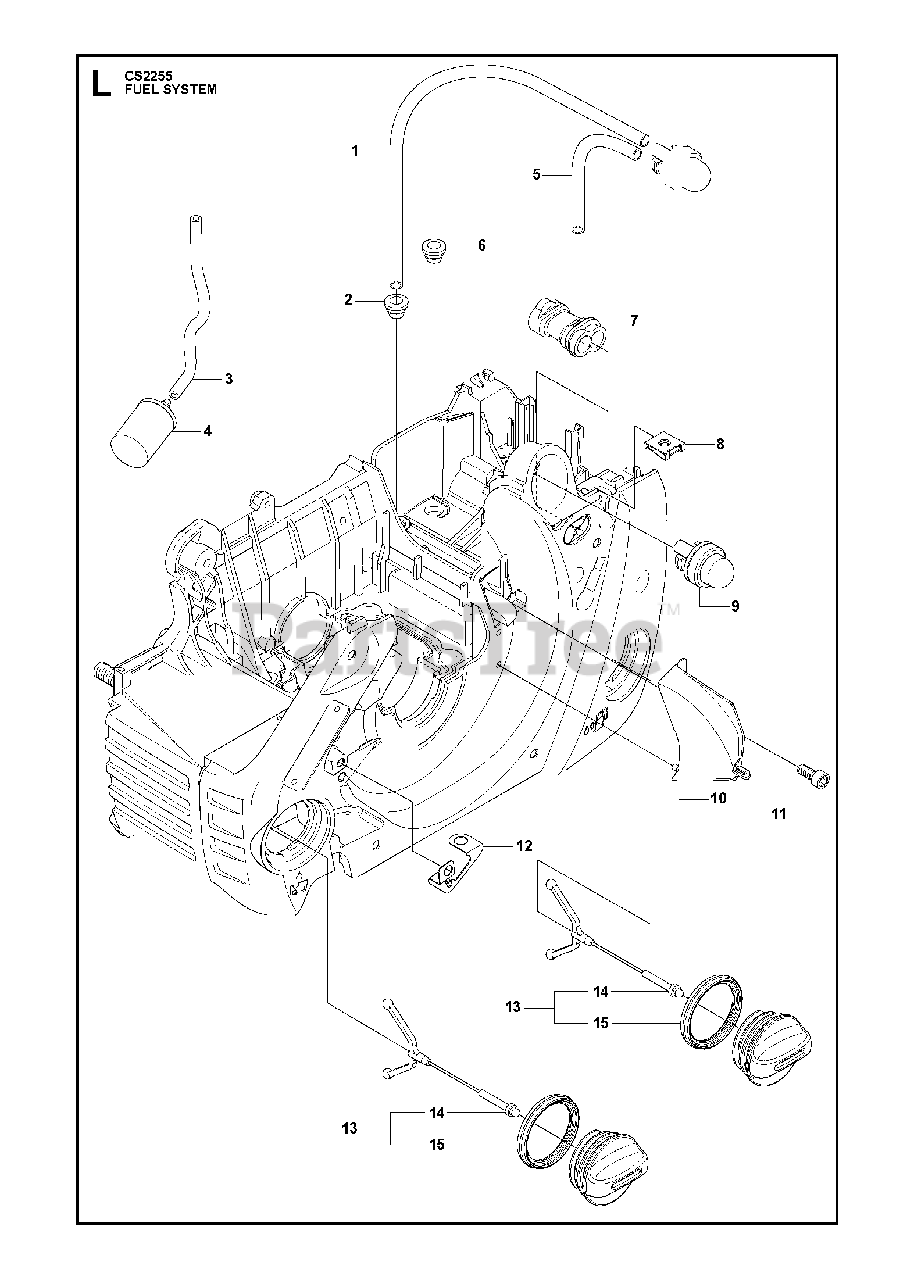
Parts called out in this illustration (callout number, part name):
2	FUEL TANK BUSHING
3	FUEL HOSE
4	FUEL FILTER
5	FUEL HOSE/38MM
6	FUEL TANK BUSHING
7	GUIDE SLEEVE CARB
9	AIR PURGE BUBBLE
12	SWITCH PLATE
13	TANK CAP ASSY
14	HOLDER
15	SEALING
